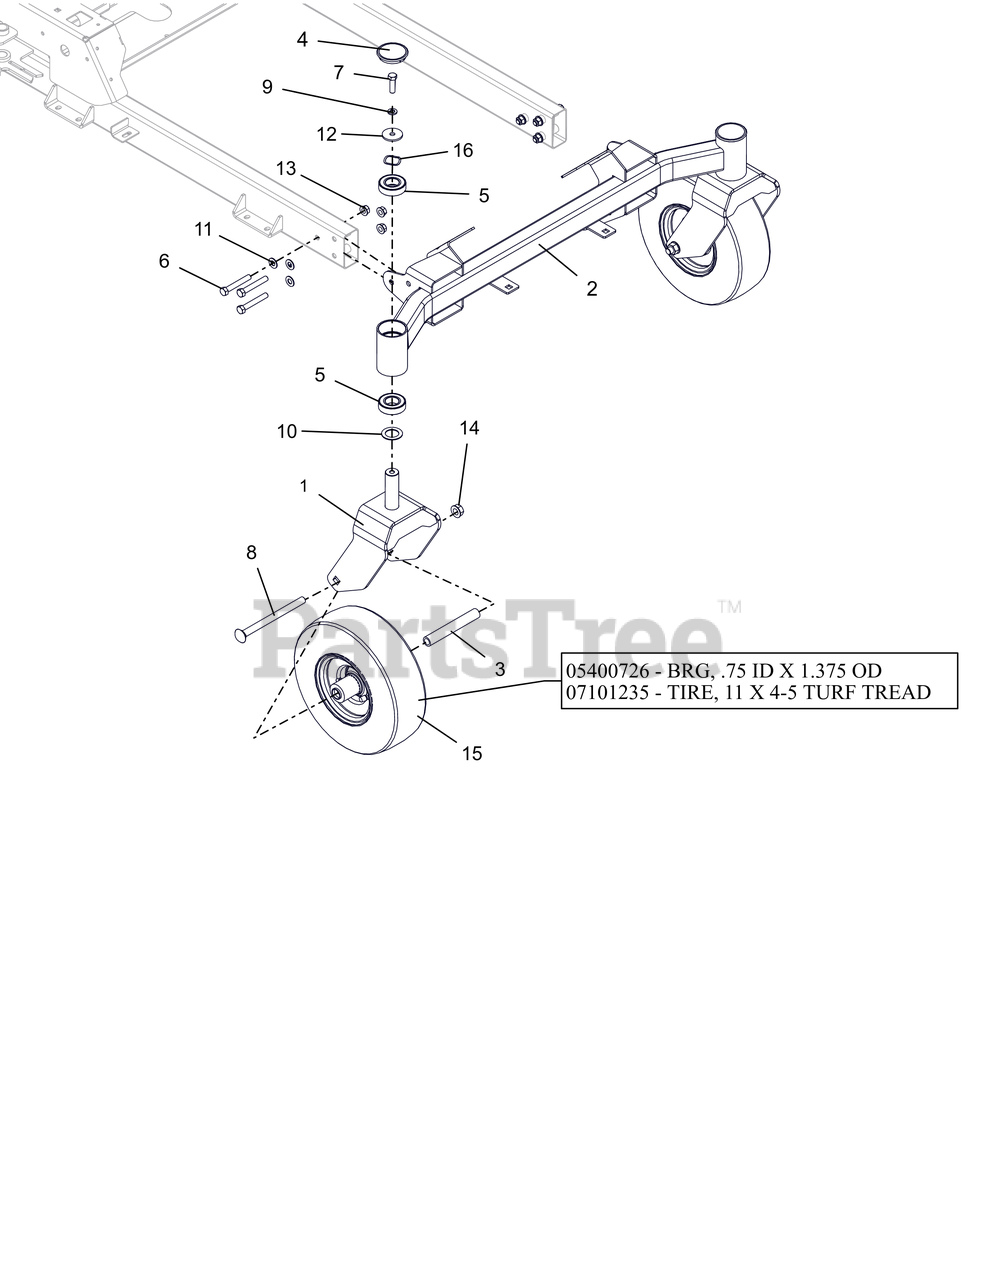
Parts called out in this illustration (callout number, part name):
1	WMT, CASTER FORK
2	WLDMT, AXLE FRONT
3	SPACER, ROLLED WHEEL
4	CAP, DUST
5	BRG,BALL 1.00X2.00X.563(1641)
6	BLT, HEX .38-16X2.50 G8 ZCC
7	BLT, HEX .38-16X1.25 G5 ZCC
8	BLT, RHSN .50-13X6.50 G5 ZCC
9	WSHR,LK-REG .375X.094 ZCC
10	WSHR-HRD-THRS 1.007X1.542X.062
11	WSHR,FLT-HRD.406X.812X.055 MZC
12	WSHR, FLT .380X1.50X.125 ZCC
13	NUT-LK-TOP-FLG .375-16 GG ZCC
14	NUT-LK-TOP-FLG .500-13 GF ZCC
15	ASM, WHL/TIRE 11X4.00-5
15	BRG, .75 ID X 1.375 OD
15	TIRE, 11X4-5 TURF TREAD
16	WSHR-WAVE 1.0X1.25X.028 .145FH
